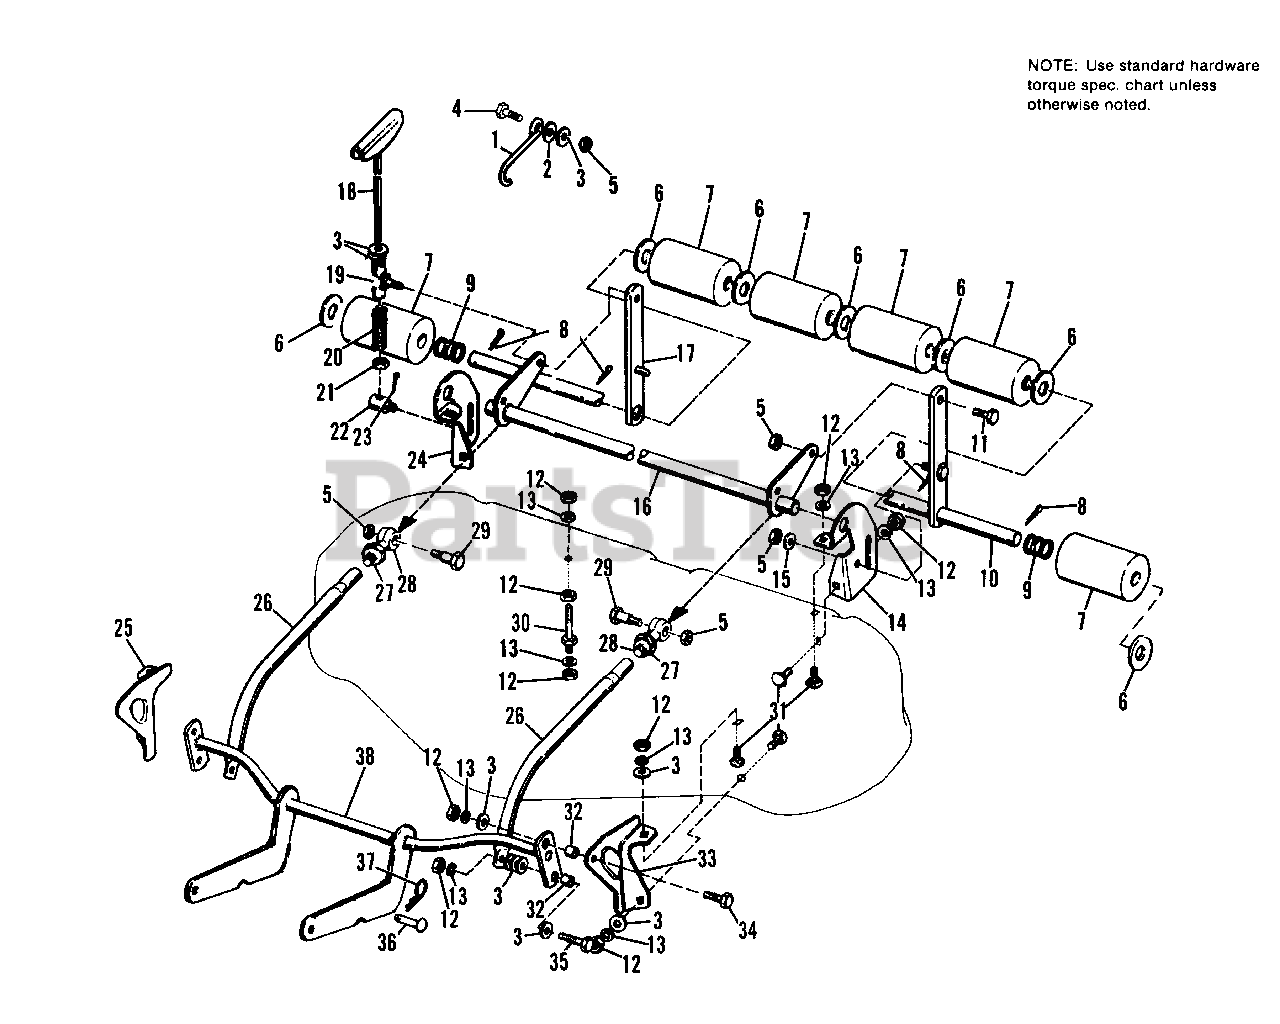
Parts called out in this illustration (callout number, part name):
2	WASHER, Special
3	WASHER, Plain, 3/8
4	CAPSCREW, Hex Hd., 3/8-16 x 1-1/4
5	LOCKNUT, Hex, 3/8-16
7	ROLLER ASSY.
8	PIN, Cotter, 3/16 x 1
9	WASHER (as required)
10	BAR & SHAFT ASSY.
11	CAPSCREW, Hex Hd., 3/8-16 x 7/8
12	NUT, Hex, Full, 3/8-16
13	LOCKWASHER, 3/8
14	BRACKET, Roller, L.H.
15	WASHER, Plain, 5/16
16	LEVER ASSY., Rear
17	BAR ASSY., Roller
18	SCREW ASSY., Adj.
19	SOCKET ASSY., Crank
21	LOCKNUT, Jam, 3/8-16
23	PIN, Cotter, 3/32 x 3/4
24	BRACKET, Roller, R.H.
25	BRACKET, Front, R.H.
26	ARM, Adjusting
27	LOCKNUT, Jam, 1/2-20
29	BOLT, Shoulder
31	BOLT, Carriage, 3/8-16 x 3/4
33	BRACKET, Front, L.H.
34	CAPSCREW, Hex Hd., 3/8-16 x 1
35	CAPSCREW, Hex Hd., 3/8-16 x 1-1/4
37	PIN, Quick
38	HITCH ASSY., Mower
